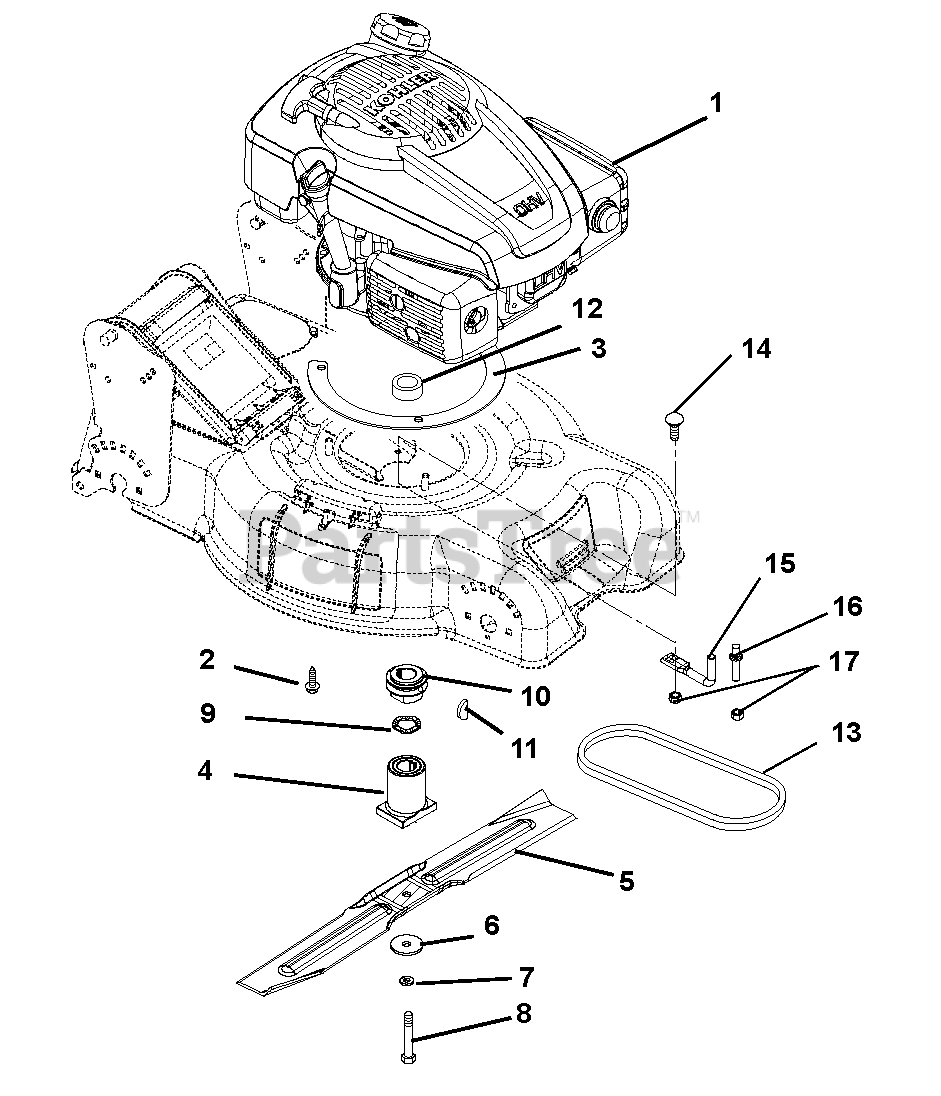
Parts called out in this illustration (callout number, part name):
1	Engine, Kohler XT-7 (911220, 222)
2	Screw, Tapping .38-16X1.00 Hex Washer Head
3	Ring, Engine Bolt
4	Adapter, Blade Hub (911220, 221, 222, 223)
5	21" Mower Blade
6	Washer, Flat Steel .39 x 1.5 x .125
7	Washer, Locking .38 x .094 Regular
8	Bolt, .38-24 x 2.5 Grade 8 (911220, 221, 222, 223)
9	Washer, Wave .885 x 1.311 x .125 (911220, 221, 222, 223)
10	Pulley, Sintered Iron LM (911222, 223)
11	Key, Woodruff .156 x .625 x .25 (911220, 221, 222, 223)
12	Spacer, .875 x 1.125 x .551 (911224)
13	Belt, 3L Wrapped 37.00"
14	Bolt, Round Head Square Neck .25-20 x .50 Grade 5
15	Finger, Belt
16	Finger, Belt
17	Nut, Locking-Flange .250-20
